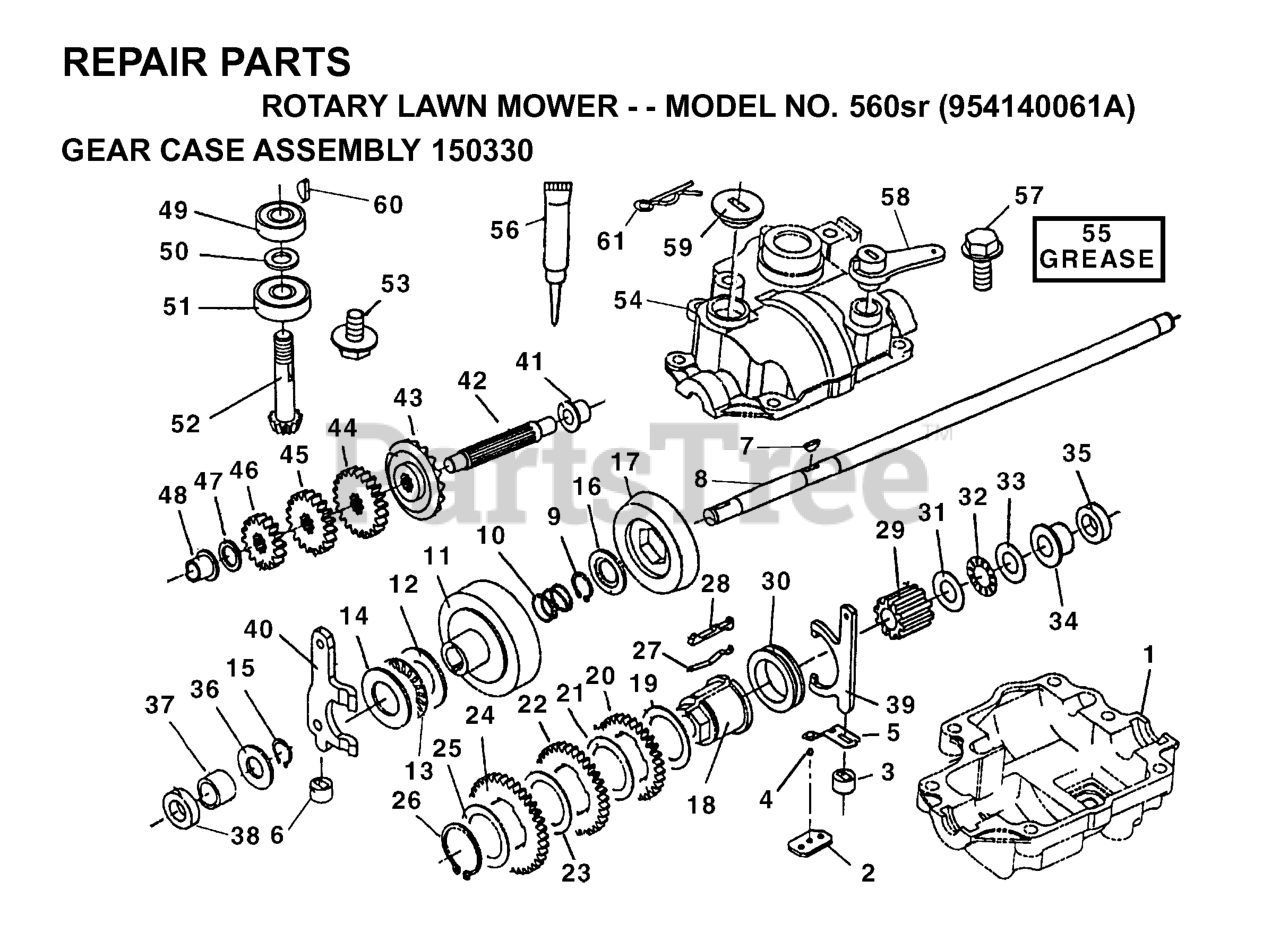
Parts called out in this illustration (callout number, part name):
3	SUPPORT FORK, SHIFT
8	AXLE, 560SR
10	SPRING, RETURN
18	SHIFT COLLAR
35	SEALING RING
38	SEALING RING
56	SEALING
58	SHIFTER ARM
